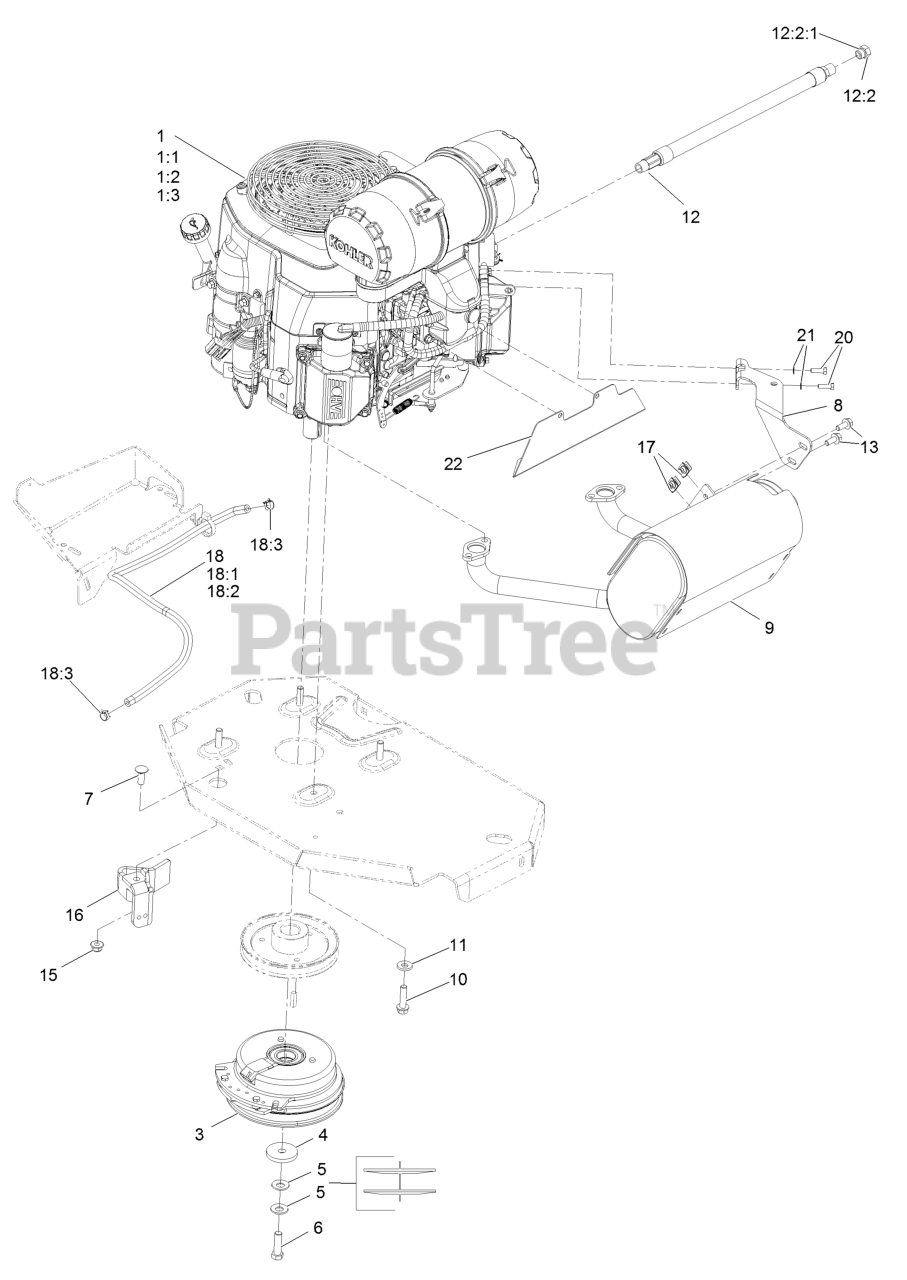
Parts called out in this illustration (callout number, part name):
1:1	Kohler 52 050 02-S Engine Oil Filter
1:2	Kohler 25 083 01-S Engine Air Filter
1:3	Kohler 25 083 04-S Safety Filter
3	CLUTCH KIT
4	WASHER-CLUTCH
5	WASHER-SPRING
6	SCREW-HH 7/16-20 X 1 1/2 W/LOCTITE
7	SCREW-CARR
8	MUFFLER BRACKET KIT
9	MUFFLER KIT
10	SCREW-HWH
11	WASHER-BELLEVILLE
12	OIL DRAIN HOSE ASM
12:2	PLUG-HH
12:2:1	O-RING
13	SCREW-HHF
15	NUT-HF, NI
16	CLUTCH-ANCHOR
18	FUEL LINE ASM
18:1	HOSE-FUEL
18:2	SLEEVE-THERMAL
18:3	CLAMP-HOSE
20	SCREW-HH M6-1 X 20Mm W/Patch
21	WASHER-SPRING
22	SHIELD-HEAT, CARBURETOR
